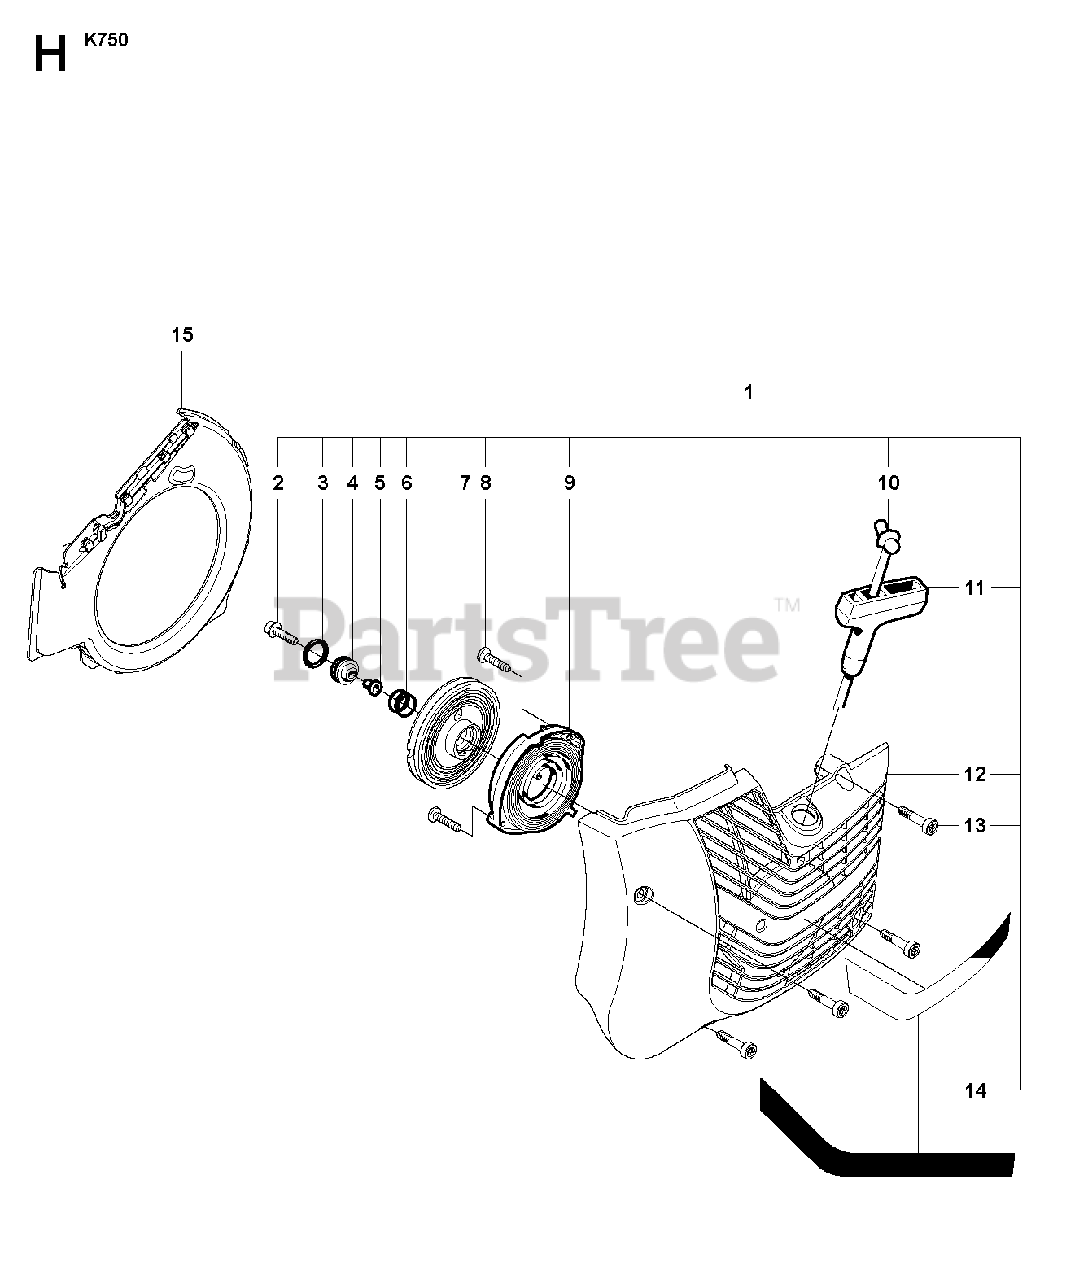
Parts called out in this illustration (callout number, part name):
1	STARTERIncl. 2 - 14
2	SCREW IHSCT
4	GROMMET
5	SPACING SLEEVE
6	COMPRESSION SPRING
7	STARTER PULLEY
8	SCREW CCRPANT
9	RECOIL SPRING
10	STARTER CORD50 m
11	STARTER HANDLE
12	STARTER COVER
13	SCREW ITXSCM
14	LABEL
15	AIR CONDUCTOR
